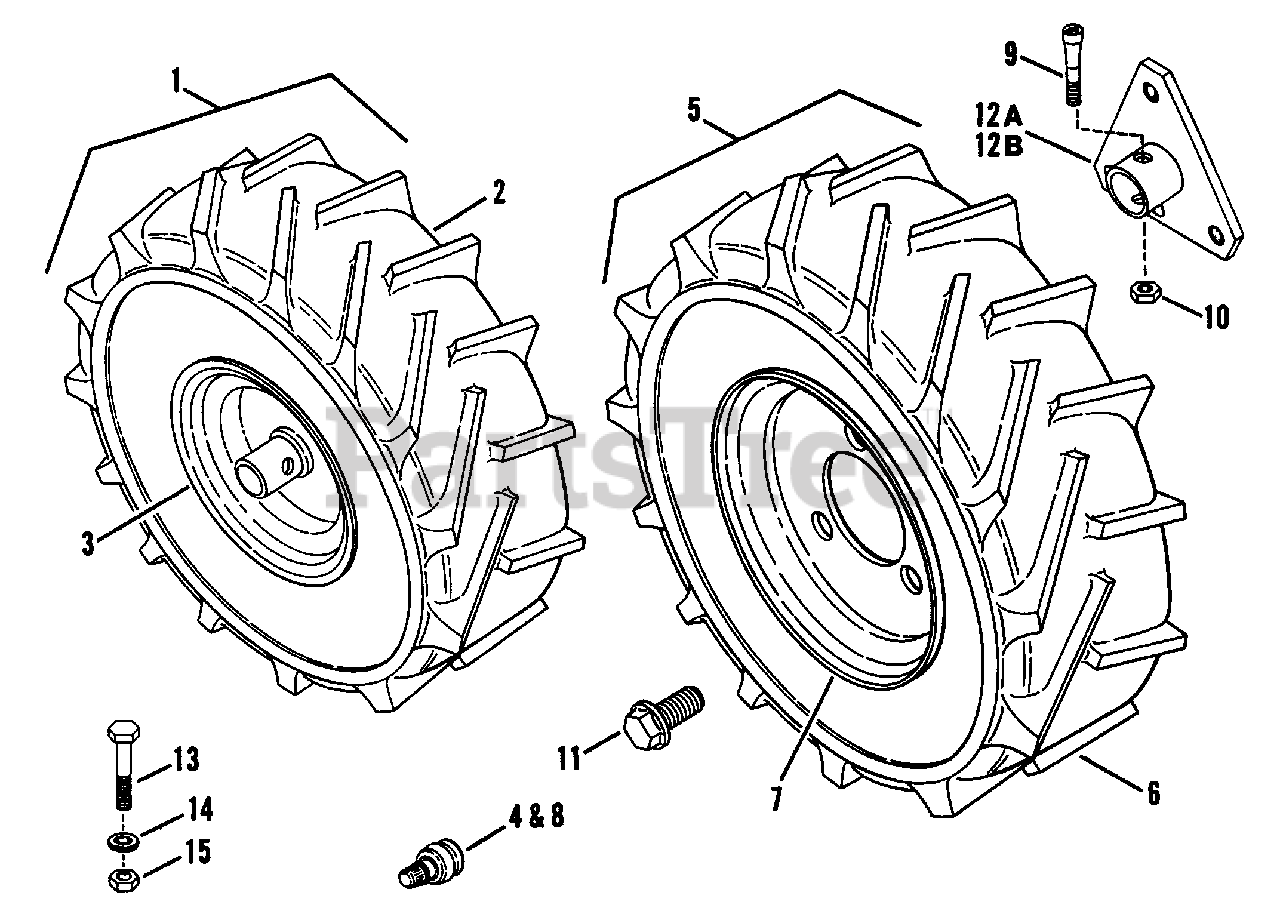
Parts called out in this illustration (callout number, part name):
1	ASSEMBLY, Right Wheel- 5HP
1	ASSEMBLY, Left Wheel- 5HP
2	TIRE, 13x5.00-6 (Lug)
4	VALVE, Air (Snap-in)
5	ASSEMBLY, Left Wheel- 8HP
5	ASSEMBLY, Right Wheel- 8HP
6	TIRE, 16x4.80-8 (Lug)
7	RIM
8	VALVE, Air (Snap-in)
9	BOLT, 5/16-24 Tapered (8HP)
10	NUT, 5/16-24 Hex Lock, Grade C (8HP)
11	SCREW, 1/2-20 x 3/4" Hex Head Cap, Grade 2 (8HP)
12A	HUB, Wheel Structure
12B	HUB, Wheel Structure
13	SCREW, 5/16-24 x 1-5/8" Hex Head Cap, Grade 5 (5HP)
14	WASHER, 5/16 Internal Tooth Lock (5HP)
15	NUT, 5/16-24 Hex
